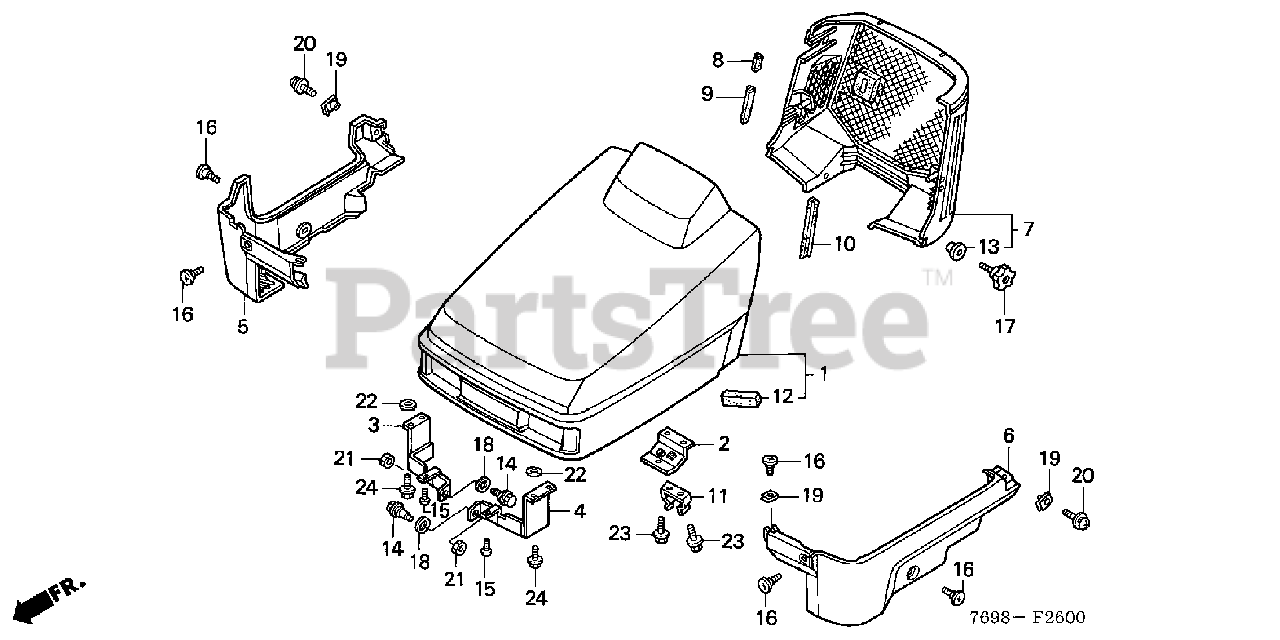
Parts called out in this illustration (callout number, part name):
1	HOOD *R165* (JOLLY RED)
2	BRACKET, HOOD STRIKER
3	HINGE, R. HOOD
4	HINGE, L. HOOD
5	SKIRT, R. SIDE *R165* (JOLLY RED)
6	SKIRT, L. SIDE *R165* (JOLLY RED)
7	COVER, STEERING COLUMN *NH105* (MAT BLACK)
8	SEAL A, COLUMN COVER (20MM)
9	SEAL B, COLUMN COVER (70MM)
10	SEAL C, COLUMN COVER (140MM)
11	STRIKER, HOOD
12	SEAL, INSTRUMENT SHOULDER (60MM)
13	COLLAR A, FENDER SETTING
14	BOLT, HINGE (10MM)
15	SCREW, VISOR SETTING
16	SCREW, METER VISOR SETTING
17	BOLT, KNOB (6MM)
18	WASHER, LOCK (B)
19	NUT, CLIP (6MM)
20	SCREW-WASHER (6X16) (NOT AVAILABLE)
21	NUT, HEX. (10MM)
22	WASHER, PLAIN (6MM)
23	BOLT, FLANGE (6X12)
24	BOLT, FLANGE (6X14)
